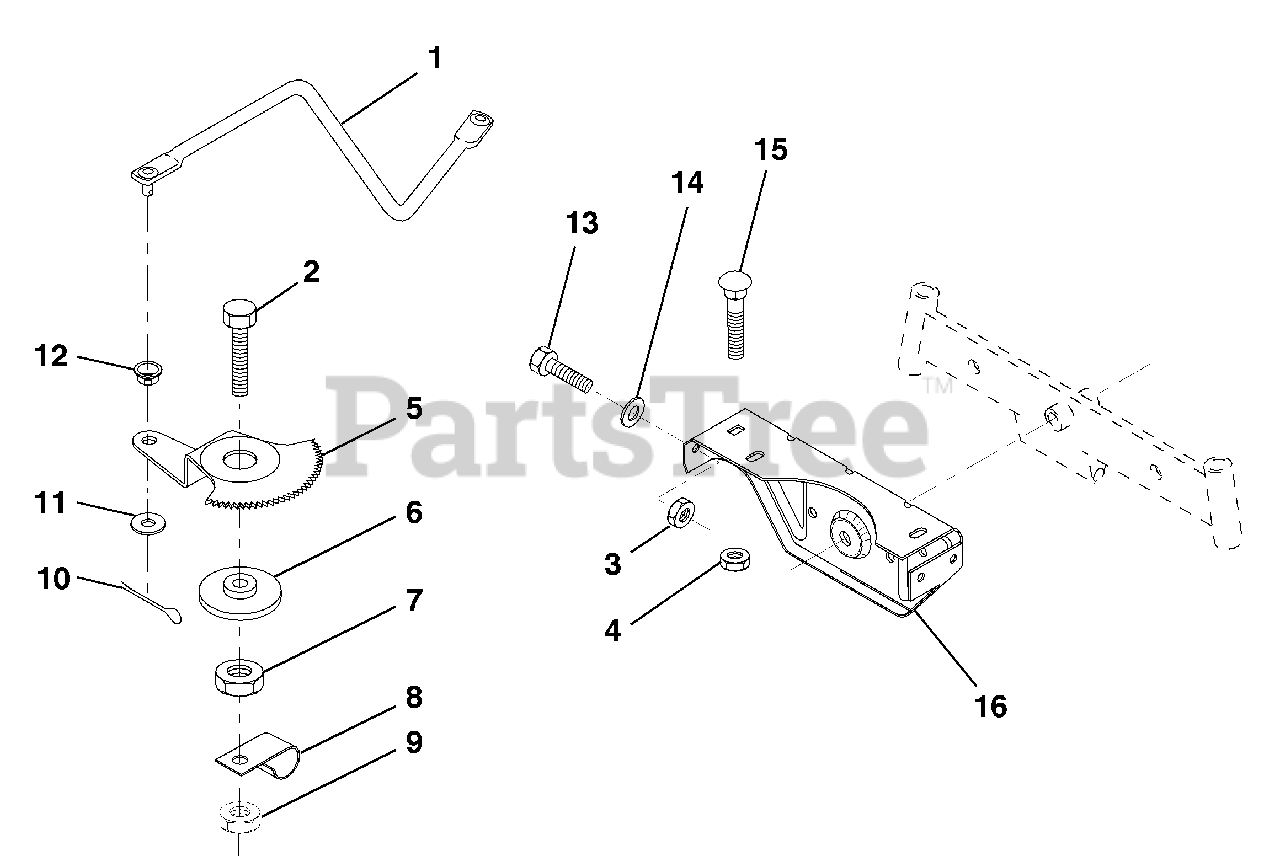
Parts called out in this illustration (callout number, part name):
1	Link, Drag
2	Bolt, Fin Hex 1/2-13 x 1-3/4
3	Nut, Crownlock 5/16-18
4	Nut, Crownlock 3/8-16 UNC
5	Gear, Sector
7	Nut, Heavy Hex Top Lock 1/2-13 UNC
8	Clip, Insulated
9	Nut, Crownlock 3/8-16
10	Pin, Cotter 1/8 x 3/4
11	Washer, 13/32 x 13/16 x 16 Ga.
13	Bolt, Hex Hd. 5/16-18 UNC x 3/4
14	Washer 11/32 x 7/8 x 16 Ga.
15	Bolt, Carriage 3/8-16 UNC x 3/4
16	Support, Front Axle
